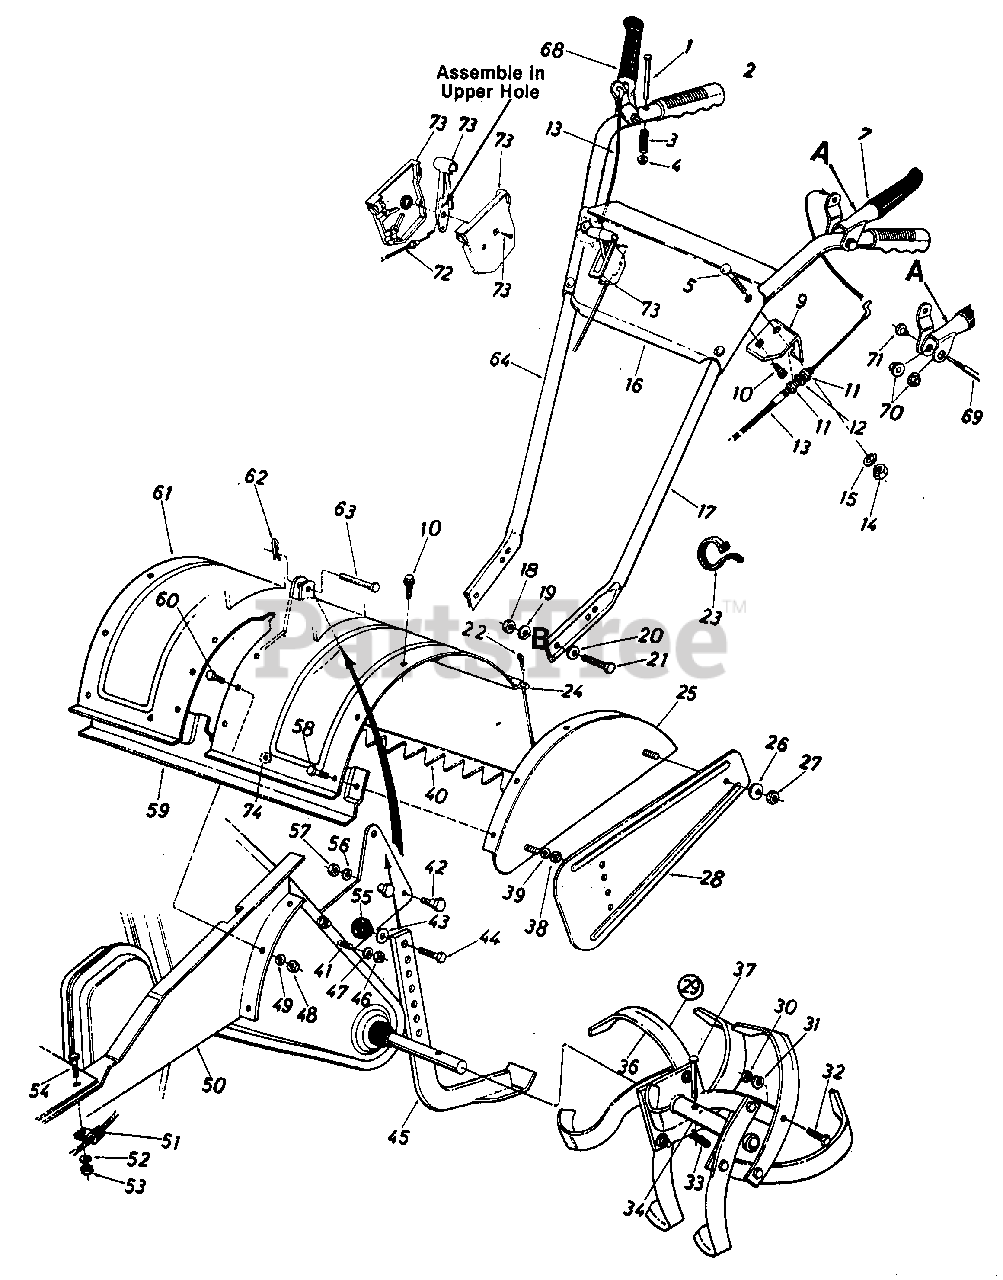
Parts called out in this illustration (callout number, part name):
1	Clevis Pin 1/4 " Dia. x 2.25"
3	Compression Spring .33" O.D. x 1.2" Lg.
4	Cap Speed Nut 1/4" Rod
5	Carr. Bolt 5/16-18 x 1.75"*
7	Clutch Grip Ass'y. L.H.
9	Clutch Cable Bracket
10	Hex Wash. S-Tap Scr. 5/16-18 x .62" Lg.
11	Hex Nut 5/16-24 Thd.
12	L-Wash. 5/16" I.D.*
13	Clutch Control Cable
14	Hex Nut 5/16-18 Thd.*
15	L-Wash. 5/16" I.D.*
16	Handle Panel
19	L-Wash. 3/8" I.D.*
20	Bell-Wash. 3/8" I.D.
21	Hex Bolt 3/8-16 x 1.00" Lg.*
22	Cotter Pin 3/32" Dia. x 3/4*
23	Cable Tie
24	Tiller Flap Rod
27	Hex Nut 5/16-18 Thd.*
29	Tine Ass'y. Comp. R.H.
30	Hex Nut 3/8-24 Thd.*
31	L-Wash. 3/8" I.D.*
32	Hex Bolt 3/8-24 x 1.25" Lg.*
33	Hairpin Cotter
34	Tine Adapter Ass'y.
34	Tine 12" R.H.
38	Hex Nut 5/16-18 Thd.*
39	L-Wash. 5/16" I.D.
40	Tine Shield Flap
41	Hex Bolt 5/16-18 x 1.0" Lg.*
42	Shld. Bolt 1/2" Dia. x .426"
43	Fl-Wash. 3/8" I.D. x 5/8" O.D.
44	Hex Bolt 3/8-16 x 314" Lg.*
45	Depth Bar Ass'y.
46	Hex Nut 5/16-18 Thd.*
47	L-Wash. 5/16" I.D.*
48	Hex Nut 5/16-18 Thd.*
49	L-Wash. 5/16" I.D.*
52	L-Wash. 5/16" I.D.*
53	Hex Nut 5/16-18 Thd.*
54	Hex Bolt 5/16-18 x 314" Lg.*
55	Ball Knob 1/4" Dia. x 3/8-16 Thd.
56	L-Wash. 3/8" I.D.*
57	Hex Nut 3/8-16 Thd.*
58	Hex Bolt 5/16-18 x .75" Lg.*
59	Bracket Reinforcement
60	Hex Bolt 5/16-18 x .75" Lg.*
61	Tine Shield Ass'y.
62	Hairpin Cotter
63	Clevis Pin 3/8" Dia.
69	Shoulder Bolt .38" Dia. x 1.53" Lg.
70	Hex Flange Plastic Bearing
71	Shoulder Nut 1/4-20 Thd.
72	Throttle Control Wire
73	Throttle Control Box Ass'y.
74	Bell-Wash. 5/16" I.D.
